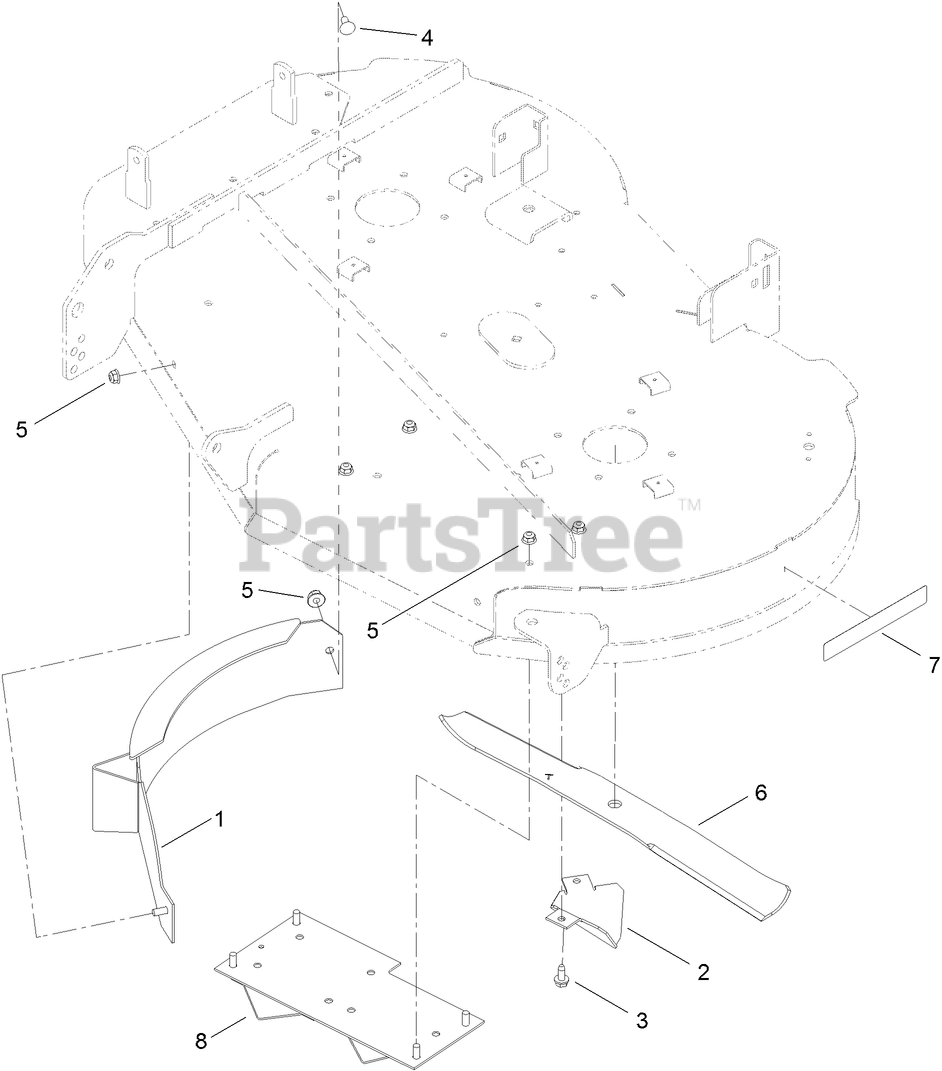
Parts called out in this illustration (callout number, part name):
1	BAFFLE ASM
2	KICKER-FLANGED
3	SCREW-HWHTF
4	BOLT-CARR
5	NUT-HF, NI
7	DECAL-RECYCLER
8	KICKER ASM
